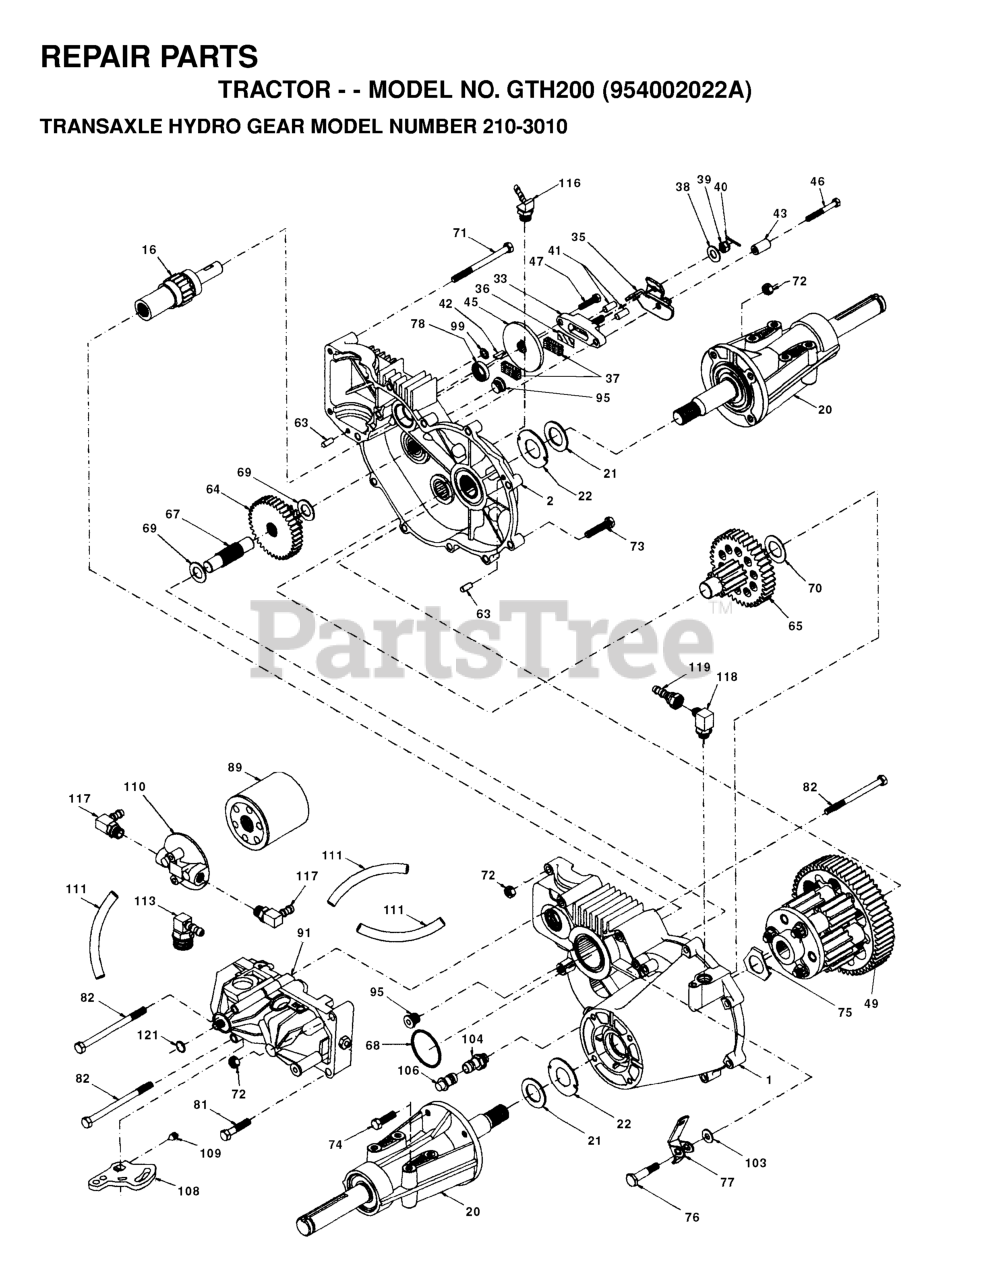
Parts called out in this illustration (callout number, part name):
1	HOUSING.TRANSAXLE.70536
2	ASSEMBLY, RH HOUSING
16	BRAKE SHAFT KIT #62877
20	AXLE.MOUNTING.HORN.70087
21	WASHER 44805
33	BRAKE YOKE ASSEMBLY
35	BRACE ARM 50214
36	PUCK PLATE 44134
37	BRAKE PUCK (44132)
38	WASHER .34X.88X.06.44130
39	CASTLE NUT
40	PIN.COTTER.44101.
41	BRAKE PIN 44127
42	KEY.HIPRO.44143
43	SPACER 50259
45	BRAKE.DISC.44090.
46	BOLT 44276
47	BOLT W/NYLOCK 44433
49	DIFFERENTIAL ASSEMBLY
63	DOWEL.PIN.44757.HYDRO
64	GEAR 17T 44775
65	PINION DR FINAL 70051
67	JACKSHAFT.44779.HYDRO
68	O-RING #44781
69	WASHER.44795.
70	WASHER.44794.HYDRO
71	BOLT HXHD 44827
72	HEX LOCK NUT, 5/16-18
73	BOLT, HEX5/16-18X1-1/2
74	HEX CAP SCREW, 5/16-18X1
75	WASHER.DIFFERENTIAL.44880.HYD
76	BOLT.SHOULDER.44785.
77	FREE WHEEL ACTUATING ARM 44786
78	SEAL OIL 70719
82	BOLT 5/16 44820
89	FILTER
91	PUMP BD-10C-118
95	PLUG.9005110-5600
103	WASHER 50169
104	CAP, VENT ASSY
106	O-RING KIT 70110
108	ARM CONTROL 45007
109	SCREW.SET.50018
110	FILTER HEAD 50207 HYDRO
111	HOSE.50208.HYDRO
113	FITTING.9/16 SAE.50210.
116	FITTING.9/16 SAE.50213.
117	FITTING 50249 HYDRO
118	FITTING 90 DEG #6 FLARE MALE
119	FITTING 90 DEG #6 FEMALE SAE
121	RING RETAINING 2003016
